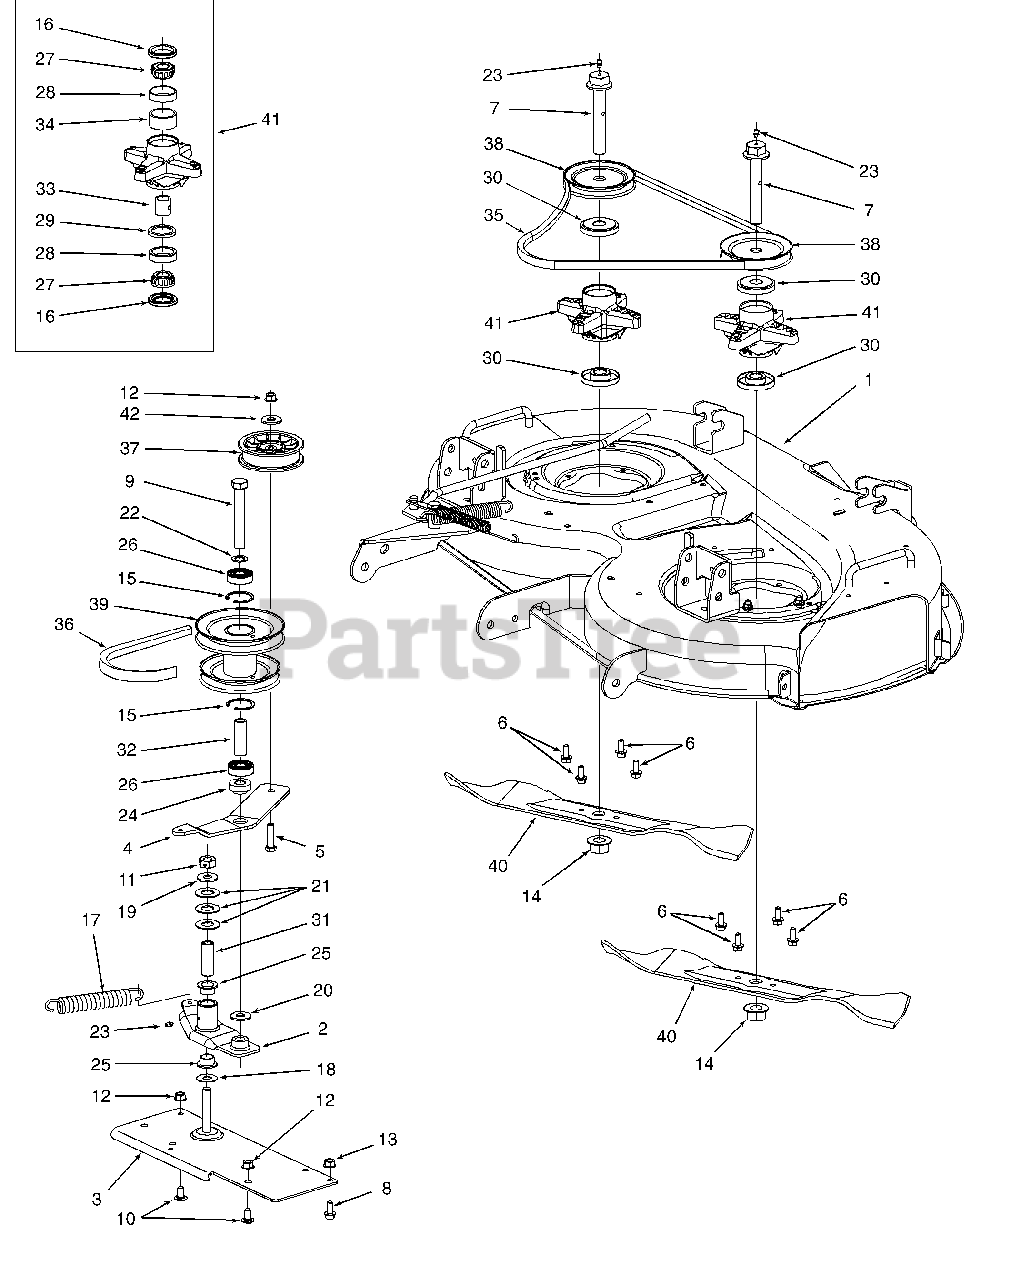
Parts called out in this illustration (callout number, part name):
6	Screw, Hex Wash Hd TT Tapp 5/16-18 x .75
7	Bolt, Spindle, 3/4-16 x 4.25
8	Screw, Hex Cap, 5/16-18 x .75 GR5
9	Screw, Hex Cap, 5/16-18 x 4.25 GR5
10	Bolt, Carriage, 3/8-16 x .75
11	Nut, Hex Center Lock, 1/2-20
12	Nut, Hex Flange Lock, 3/8-16
13	Nut, Hex Flange Lock, 5/16-18
14	Nut, Hex Flange, 3/4-16
15	Ring, Internal Snap
16	Seal, Oil. 1.25 x 1.874 x .25
17	Spring, Extension, 1.0 OD x 6.14
18	Washer, Flat, .513 x 1.25 x .036
19	Washer, Flat, .5 x 1.25 x .10
20	Washer, Flat, .64 x 1.24 x .06 Hdn
21	Washer, Flat, .76 x 1.49 x .06 Hdn
22	Washer, Flat, 5/8 x 1.0 x .063
23	Fitting, 3/16 Drive Lube
24	Spacer, Shoulder
25	Bearing, Flange, 3/4 ID x .52
26	Bearing, Ball, .625 x 1.57 x .47
27	Cone, Bearing
28	Cup, Bearing
29	Spacer, Bearing
30	Spacer, Deck Spindle
31	Spacer, .50 x .75 x .2.25
32	Spacer, .635 x 2.0
33	Spacer, Bearing, .78 x .963 x .7777
34	Spacer, Bearing 1.615 x 1.86 x .8427
35	Belt, Spindle, A-Section x 64.1
36	Belt, PTO, B-Section x 70.0
37	Pulley, Flat Idler, 3.5 OD
38	V-Pulley, 4.0 Dia
39	Pulley, Double
40	Blade, 3 in One, 21.20 Lg
41	Spindle Assembly, Blade
42	Washer, Flat
